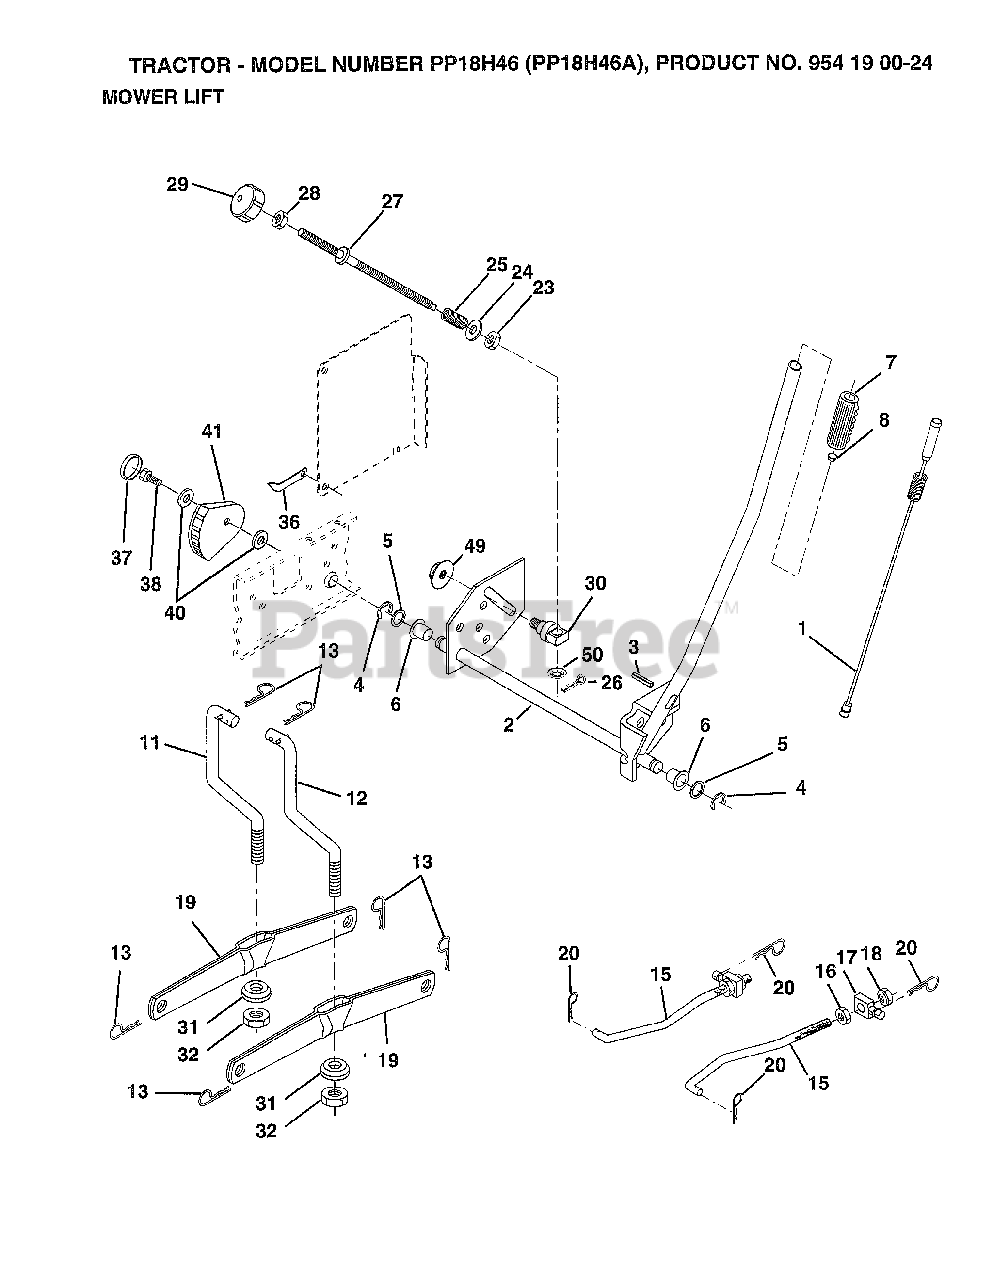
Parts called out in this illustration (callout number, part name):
1	WIRE ASM W.SPRING
2	"SHAFT ASM LIFT,RH"
3	PIN-GROOVE LT
5	WASHER
6	NYLON BEARING
7	GRIP
15	LINK.FRONT
16	NUT
17	TRUNION
18	NUT.LK.W/WSH.1/2.
19	ARM SUSP REAR
20	RETAINER SPRING
23	NUT T
24	WASHER
25	SPRING T
28	NUT
29	KNOB INF 3/8-16
30	TRUNNION
31	BEARING PVT LH
32	NUT.CROWNLOCK.3/8
36	POINTER-INDICAT
37	"PLUG,HOLE"
38	SCREW
40	WASHER
41	INDICATOR HEIGHT
49	NUT.HXFLG.LOCK.
